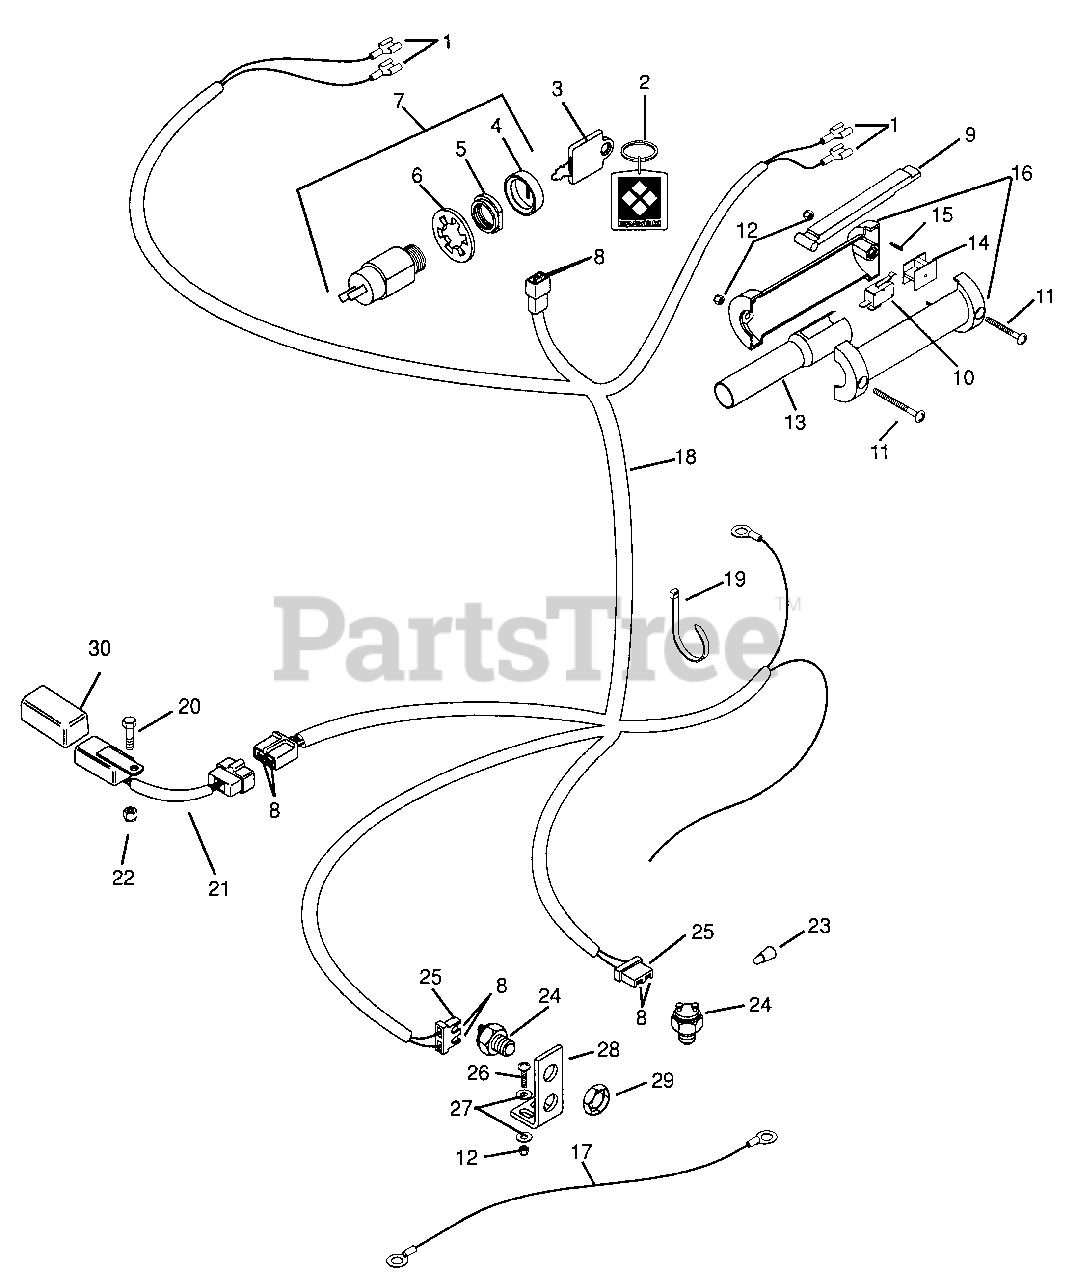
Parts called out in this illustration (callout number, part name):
1	Terminal, Female
2	Key Chain
3	Ignition Switch Key
4	Cap-Ignition Switch
5	Nut-Panel .625-32
6	Washer-Lock-Internal .625 x .045
7	Key Switch Assembly
8	Terminal
9	Lever
10	Switch
11	Screw-Machine 10-24 x 1.50
12	Nut-Locking 10-24
13	Insert, Handlebar
14	Holder, Switch
15	Pin-Roll .094 x .750
16	Handle Left Hand and Right Hand
17	Wire, Ground
18	Harness, Wiring Pro Recoil
19	Tie Wrap, Black
20	Bolt-Hex .25-20 x .75 Grade 5
21	Adapter Harness, Interlock
22	Nut-Locking-Nylon .250-20 Grade 2
23	Nut-Connector
24	Switch-Neutral Start N.C.
25	Connector, 2-Wire Switch
26	Screw-Machine 10-24 x .750
27	Washer-Flat-Steel .219 x 50 x .049
28	Bracket, Interlock Switch
29	Nut, Stamped .56-18
30	Module, Interlock, Adapter Harness
